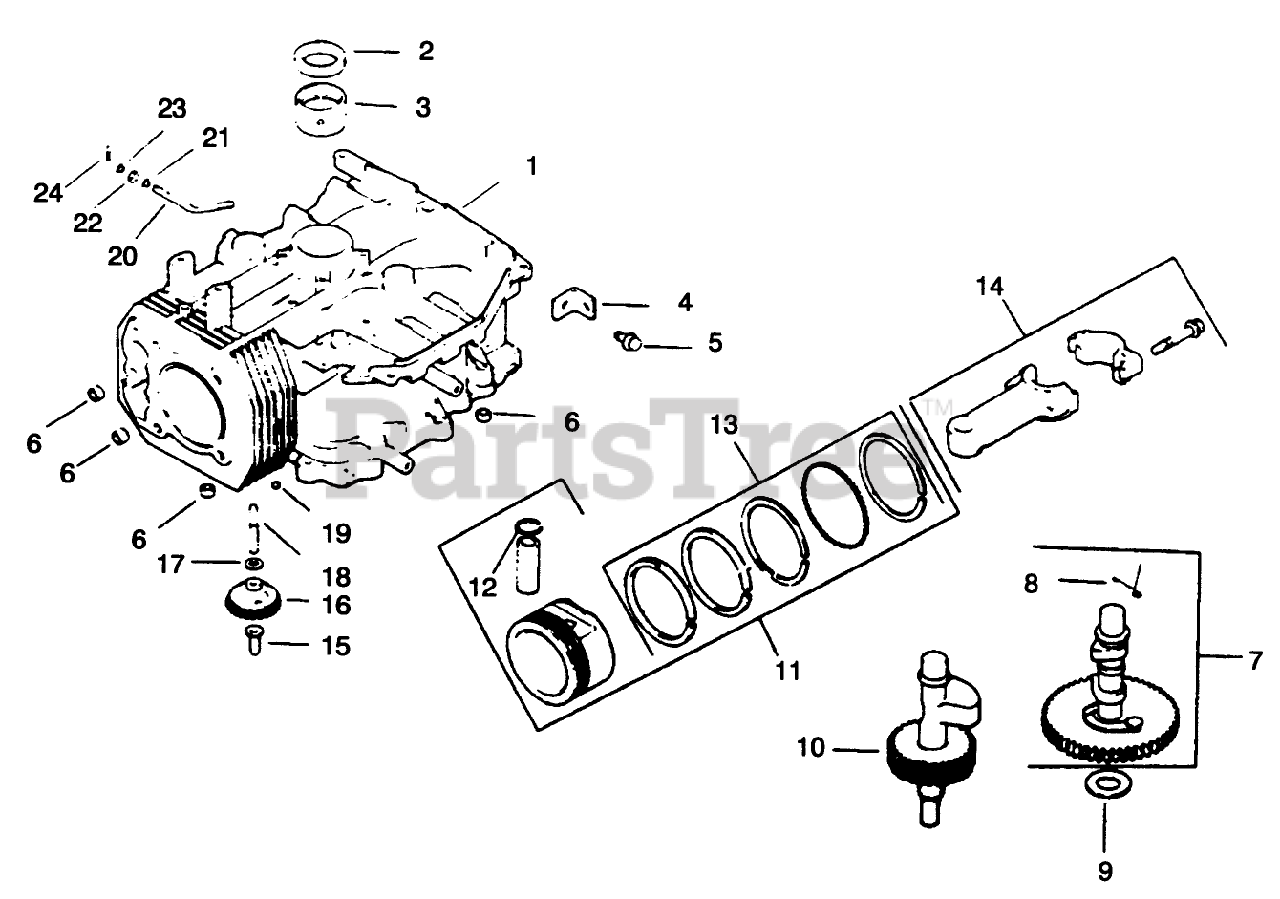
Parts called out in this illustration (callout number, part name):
1	Short Block
2	Seal-Crankshaft
3	Bearing-Crankshaft(Std.)
4	Strap-Lifting
5	Screw M8x1.25x22 (Only On: 72042, 72043, 72062, 72063)
6	Dowel-Locating
7	Camshaft Assembly
8	Spring-Actuating
9	Shim-Camshaft
10	Shaft-Balance
11	Piston W/Ring Set (Std.)
12	Retainer-Piston Pin
13	Ring Set (Std.)
14	Connecting Rod (Std.)
15	Pin-Governor Regulating
16	Gear-Governor Ass-y
18	Shaft-Governor Gear
19	Plug-Cap
20	Shaft-Govemor Cross
21	Washer
22	Seal-Cross Shaft
23	Washer-Governor Shaft (Only On: 72042, 72063, 72062, 72043)
40	Spacer
